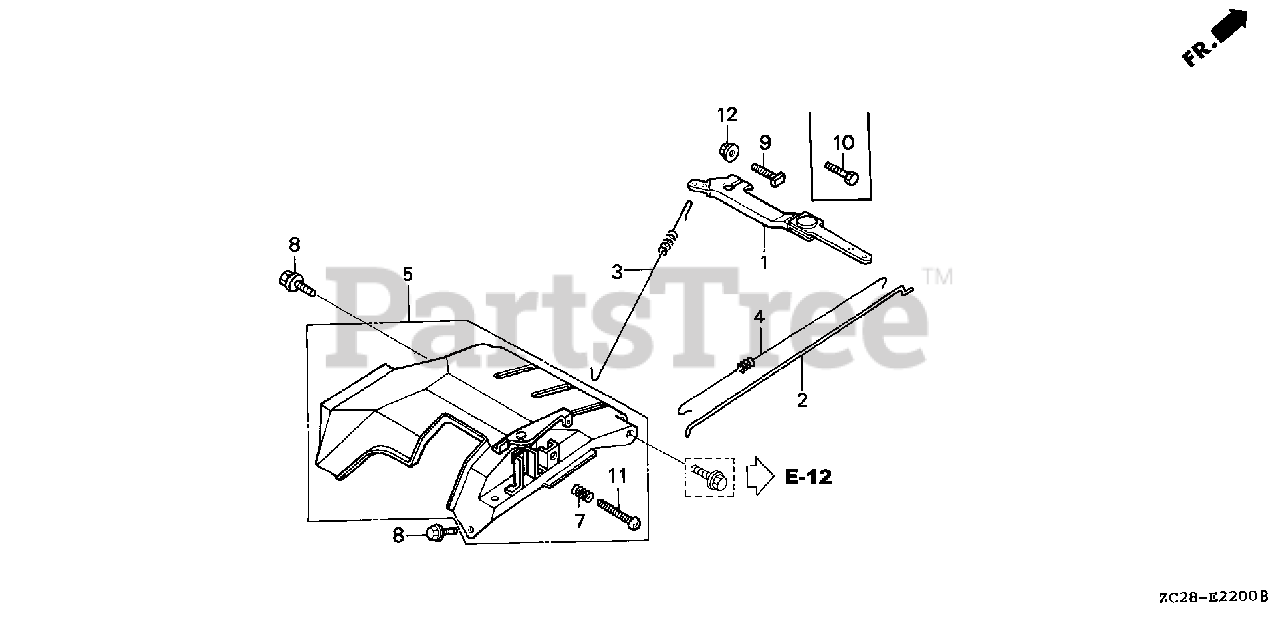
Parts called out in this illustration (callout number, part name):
1	ARM, GOVERNOR
2	ROD, GOVERNOR
3	SPRING, GOVERNOR
4	SPRING, THROTTLE RETURN
5	CONTROL ASSY.
7	SPRING, CONTROL ADJUSTING
8	BOLT, FLANGE (6X12) (CT200)
9	BOLT, GOVERNOR ARM
11	SCREW, PAN (5X35)
12	NUT, FLANGE (6MM)
